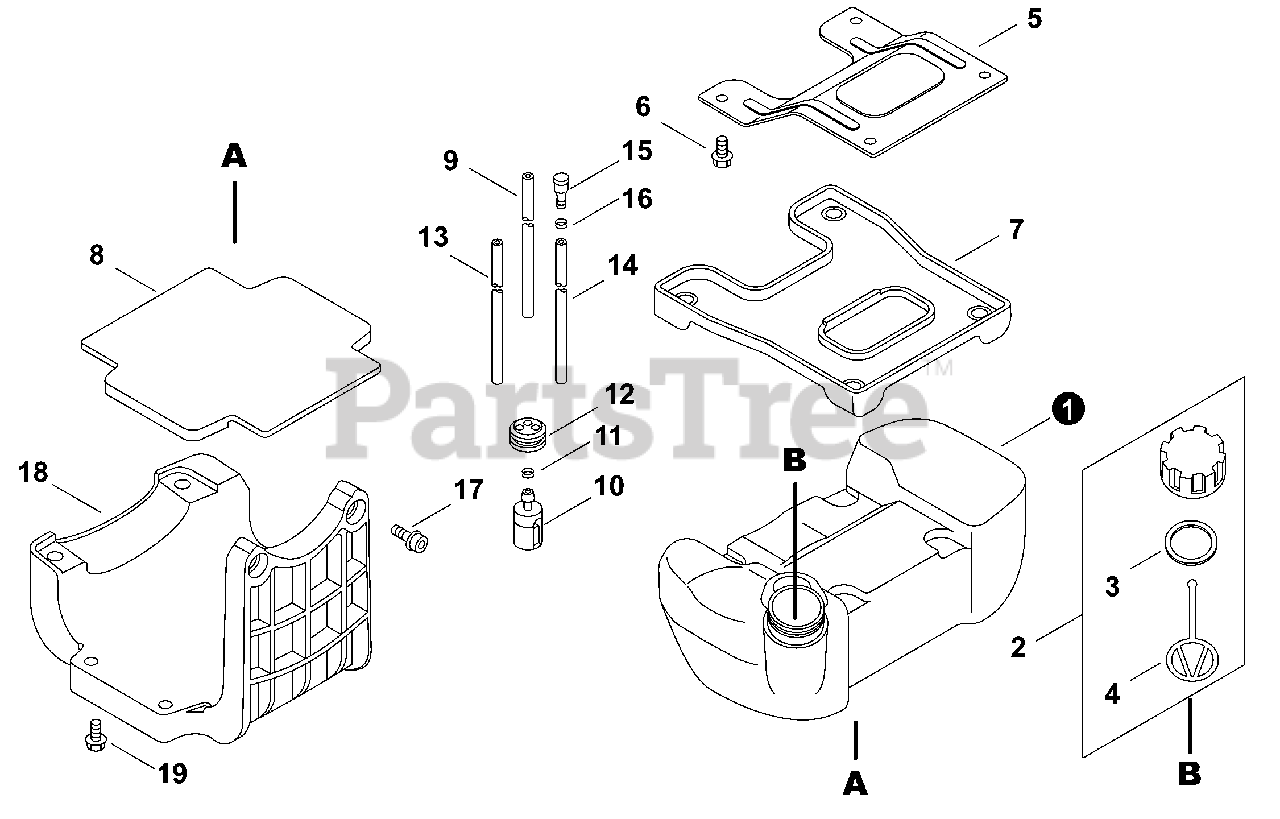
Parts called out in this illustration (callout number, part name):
1	TANK, FUEL
2	CAP ASSY, FUEL
3	GASKET, FUEL CAP
4	CONNECTOR, CAP L= 100 MM
5	BRACKET, FUEL TANK
6	BOLT 5×12
7	CUSHION, UPPER
8	CUSHION, FUEL TANK
9	PIPE, FUEL 3×6×230
10	FILTER, FUEL
11	CLIP Ø6.5 MM
12	GROMMET, FUEL
13	PIPE, FUEL 3×6×120 CLEAR
14	PIPE, FUEL 3×6×120 BLACK
15	VENT ASSY
16	CLIP Ø6.5 MM
17	BOLT 5×25
18	GUARD, FUEL TANK
19	BOLT 5×20
